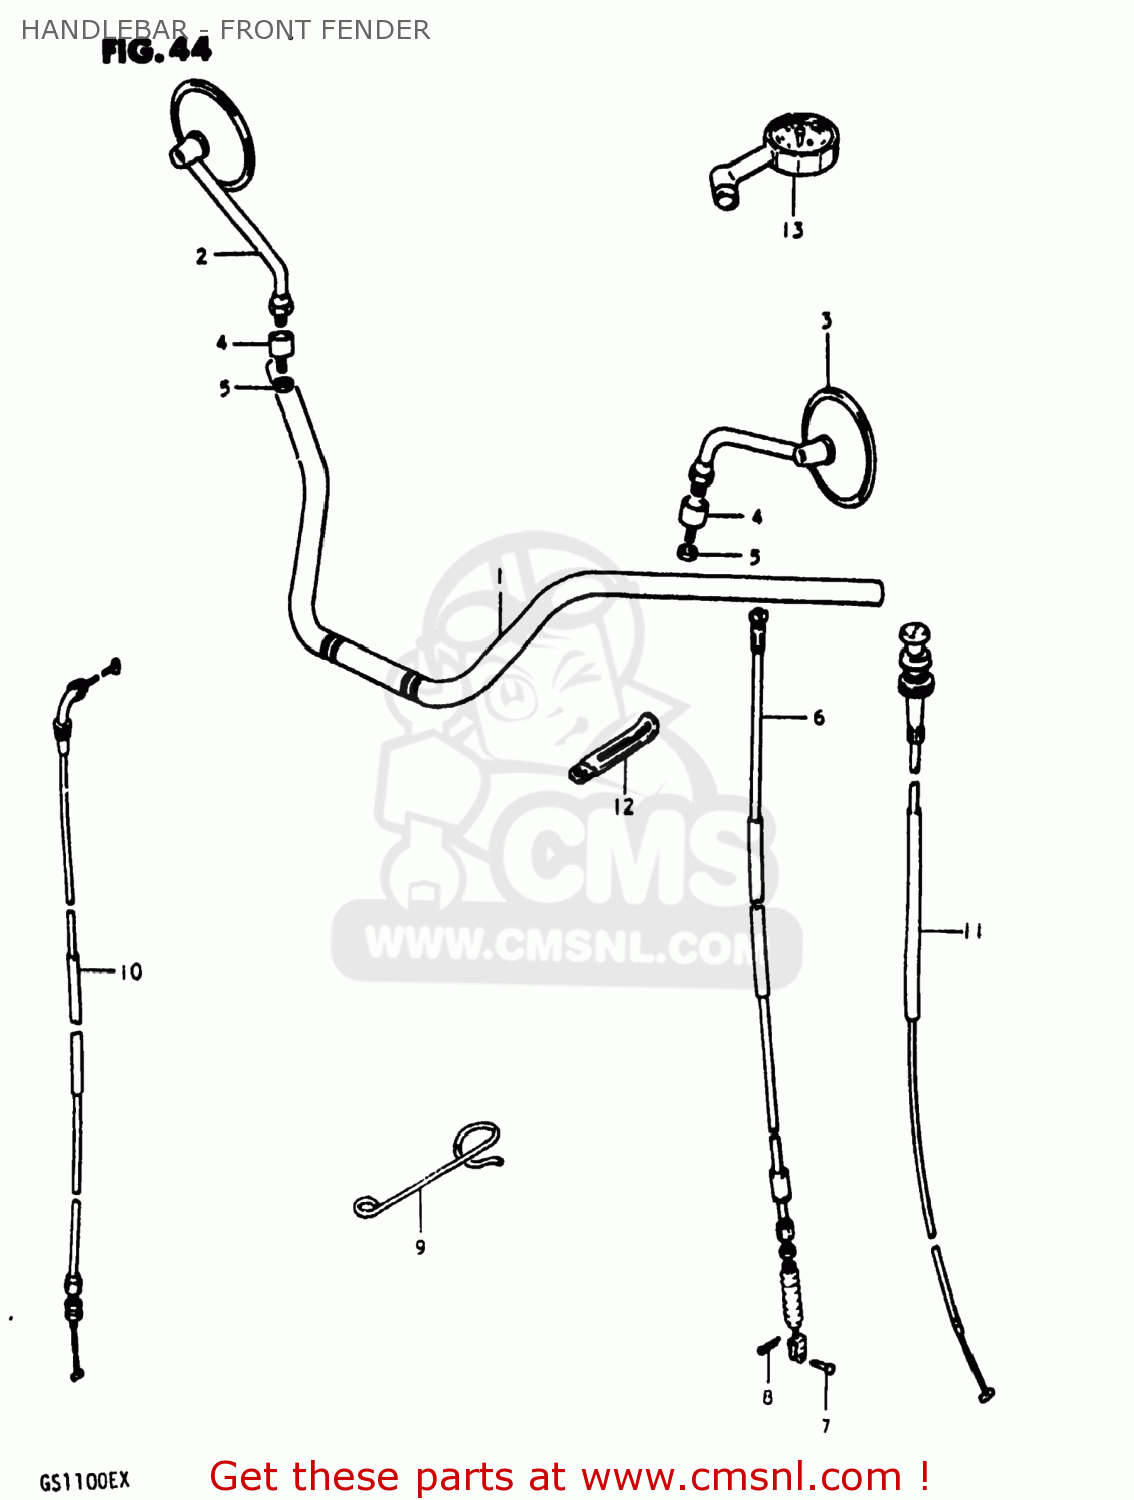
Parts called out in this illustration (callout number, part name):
1	HANDLEBAR
2	MIRROR ASSEMBLY,RIGHT
3	MIRROR ASSEMBLY,LEFT
4	CUSHION,REAR VIEW MIRROR
5	NUT
6	CABLE ASSEMBLY,CLUTCH
7	PIN(L:15)
8	PIN
9	GUIDE,CLUTCH CABLE
10	CABLE ASSEMBLY,THROTTLE
11	CABLE ASSEMBLY,STARTER
12	CLAMP
13	GAUGE ASSY,AIR PRESSURE
